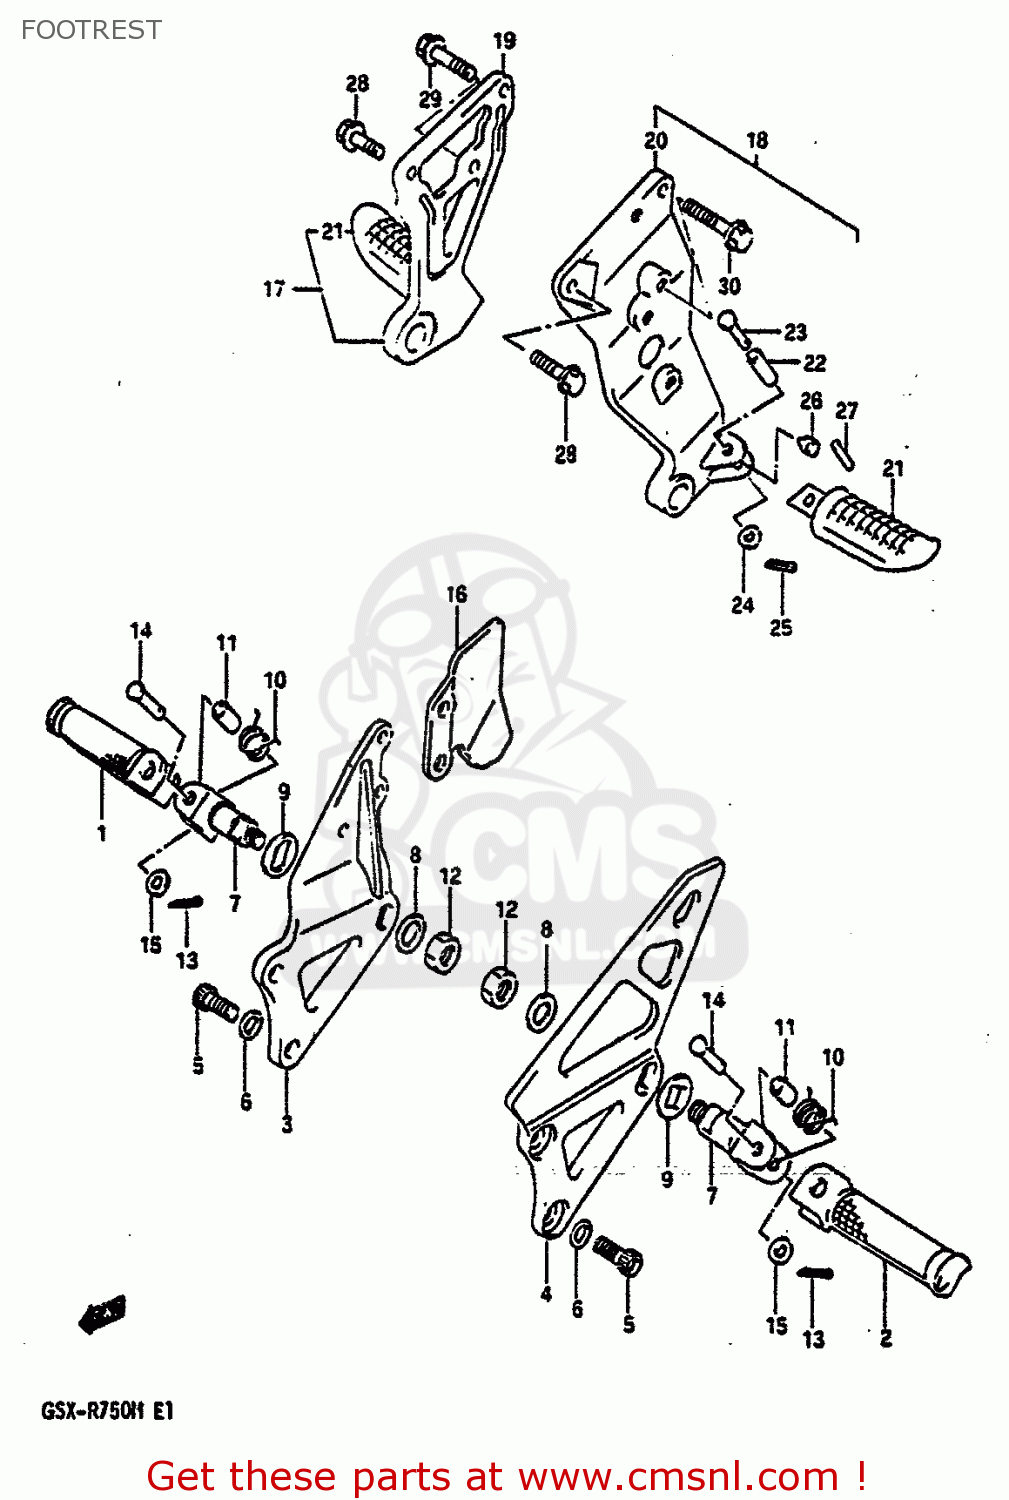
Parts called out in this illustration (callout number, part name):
1	BAR,FOOTREST,R
2	BAR,FOOTREST,L
3	BRACKET,FOOTREST,R
4	BRACKET,FOOTREST,L
5	BOLT,FOOTREST BRACKET
6	WASHER
7	BOSS,FOOTREST
8	PLATE,FOOTREST INNER
9	WASHER,FR FOOTREST
10	SPRING
11	SPACER(8.1X12X22)
12	NUT 12MM
13	PIN 20X15
14	PIN
15	WASHER
16	GUARD,FRONT FOOTREST,RIGHT
17	FOOTREST ASSY,PILLION,R
18	FOOTREST ASSY,PILLION,L
19	BRACKET,PILLION FOOTREST
20	BRACKET
21	BAR,PILLION FOOTREST R
22	SPACER(8.1X12X22)
23	PIN
24	WASHER
25	PIN 20X20
26	CUSHION,FOOTREST HOLDER
27	ROLLER,FOOTREST HOLDER
28	BOLT
29	BOLT
30	BOLT 8X40
